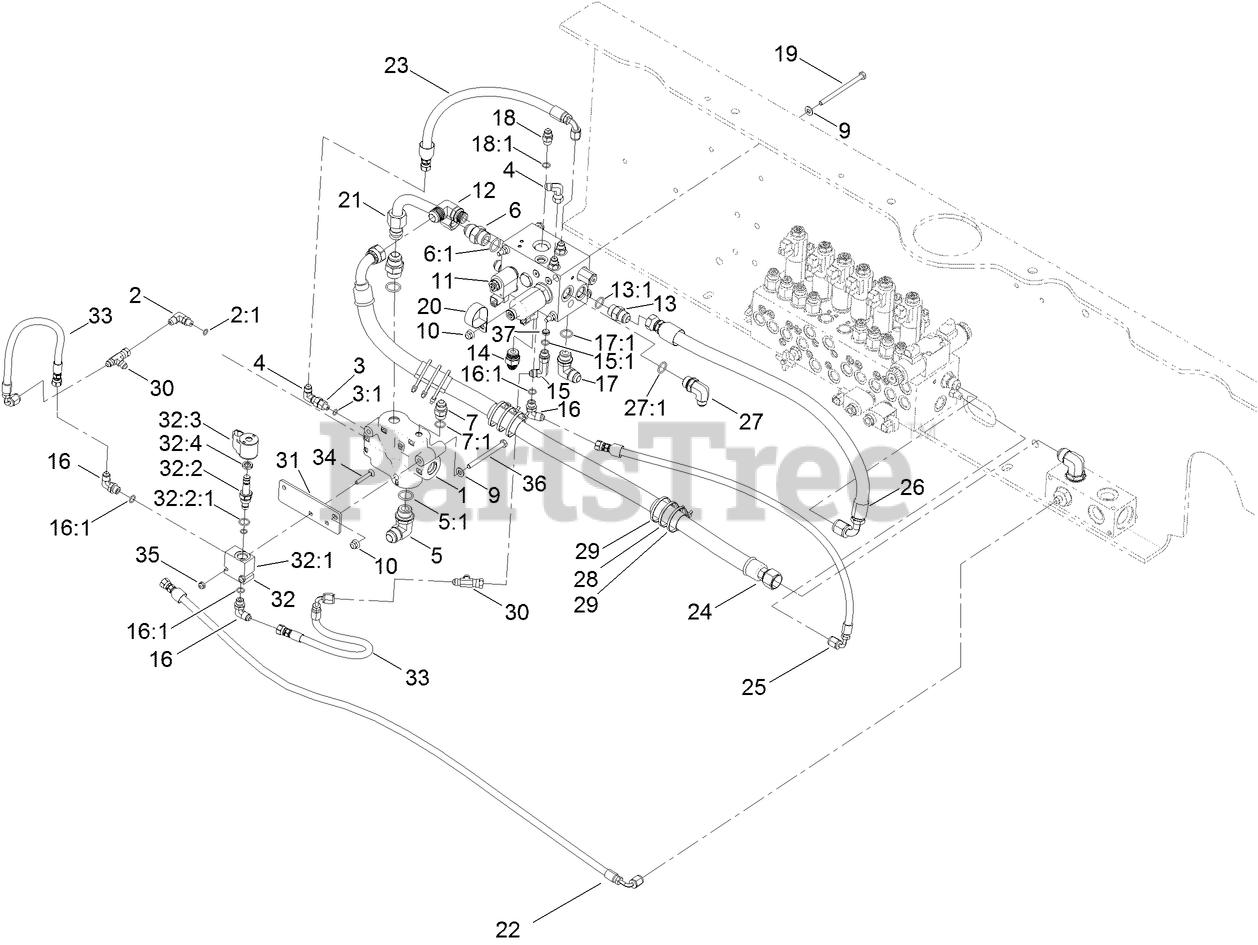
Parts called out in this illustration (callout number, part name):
1	VALVE-FLOW DIVIDER, PRIORITY
2	ELBOW-90, ADJ
2:1	O-RING
3	ADAPTER-STRAIGHT
3:1	O-RING
4	ELBOW-SWIVEL, 90 DEG
5	FITTING-ELBOW, 90 DEG
5:1	O-RING
6	FITTING-STRAIGHT
6:1	O-RING
7	FITTING-STRAIGHT
7:1	O-RING
9	WASHER-PLAIN
10	NUT-LOCK, HHF
11	VALVE-FAN DRIVE
12	FITTING-ELBOW, 90 DEG
13	FITTING-STRAIGHT
13:1	O-RING
14	FITTING-STRAIGHT
15	FITTING-ADAPTOR, 90 DEG
15:1	O-RING
16	FITTING-ELBOW, 90 DEG
16:1	O-RING
17	FITTING-ELBOW, 90 DEG
17:1	O-RING
18	FITTING-STRAIGHT
18:1	O-RING
19	SCREW-HH
20	CLAMP-R
22	HYD HOSE ASM
23	HYD HOSE ASM
24	HYD RETURN HOSE ASM
25	HYD HOSE ASM
26	HYD HOSE ASM
27	FITTING-90 DEG
27:1	O-RING
28	PROTECTOR-HOSE
29	TIE-CABLE
30	FITTING-HYD, TEE
31	PLATE-MOUNTING, VALVE
32	VALVE-SOLENOID
32:1	BODY, VALVE
32:2	VALVE-SOLENOID
32:2:1	SEAL KIT
32:4	NUT-E COIL
33	HOSE ASM
34	SCREW-CARR
35	NUT-HF
36	SCREW-HH
37	ORIFICE-DISC
